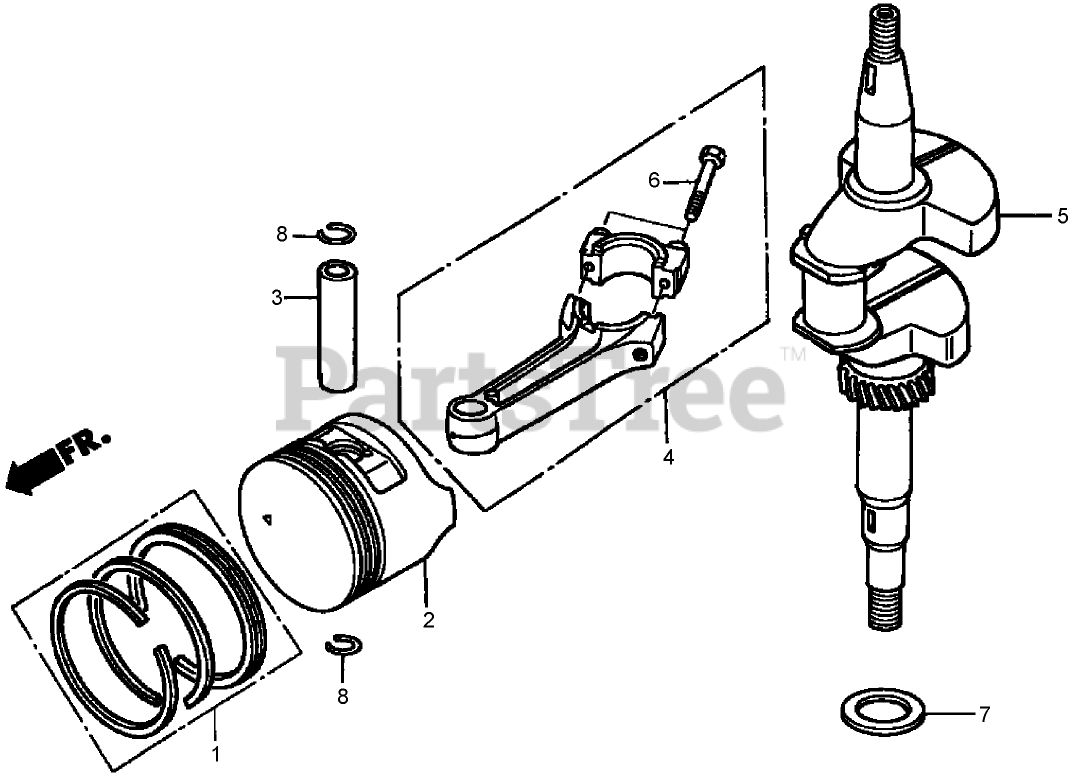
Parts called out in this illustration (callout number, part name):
1	PISTON RING SET (STD) (TEIKOKU)
1	RING SET-PISTON (STD) (NIPPON)
1	PISTON RING SET (O S 0.25) (TEIKOKU)
1	RING SET-PISTON (O S 0.25) (NIPPON)
1	PISTON RING SET (O S 0.50) (TEIKOKU)
1	RING SET-PISTON (O S 0.50) (NIPPON)
1	PISTON RING SET (O S 0.75) (TEIKOKU)
1	RING SET-PISTON (0.75) (NIPPON)
2	PISTON (STD)
2	PISTON (O S 0.25)
2	PISTON (O S 0.50)
2	PISTON (0.75)
3	PIN-PISTON
4	CONNECTING ROD ASM
5	CRANKSHAFT
6	BOLT-ROD, CONNECTING
7	WASHER-THRUST (25.6 mm)
8	CLIP-PIN, PISTON (18 mm)
